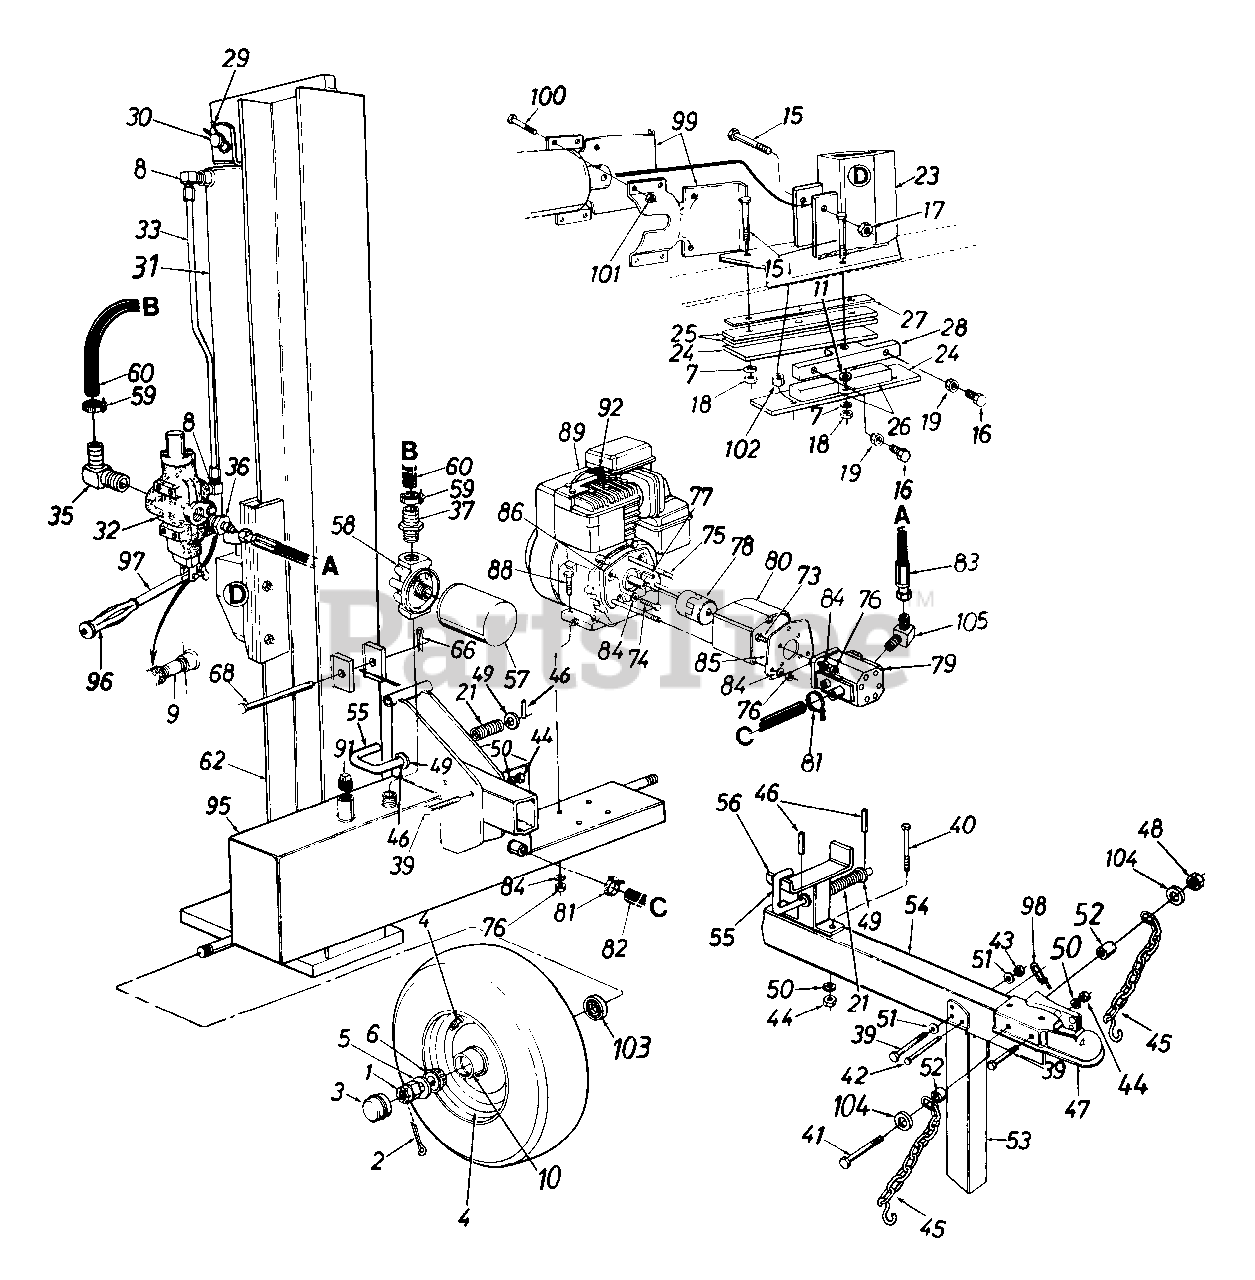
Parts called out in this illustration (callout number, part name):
1	Slotted Nut 3/4-16 Thd.
2	Cotter Pin 5/32" Dia. x 1-1/4" Lg.
5	FI-Wash..76" I.D. x 1.5" O.D.
6	Bearing Cone
7	L-Wash. 1/2" I.D.
8	90 deg. Solid Male Adapter
9	Pipe Nipple 1/2 NPT
10	Bearing Cup
11	FI-Wash..531" I.D. x.94" O.D.
15	Hex Bolt 1/2-20 x 2.75" Lg. (Grade 8)
16	Hex Bolt 3/8-24 x 1.5" Lg.
17	Hex L-Nut 1/2-20 Thd.
18	Hex Nut 1/2-20 Thd.
19	Hex Jam Nut 3/8-24 Thd. (Grade 5)
21	Comp. Spring 4" Lg.
26	Adjustable Gib
29	External Cotter Pin
30	Cylinder Mounting Pin
33	Metal Pressure Tube
35	Return Elbow
37	3/4" Hose Barb.
39	Hex Bolt 3/8-16 x 2.75" Lg. (Grade 8)
40	Hex Bolt 3/8-16 x 4" Lg.
41	Hex Bolt 3/8-16 x 4" Lg. (Grade 5)
42	Clevis Pin 5/16 x 2.5" Lg.
43	Hex L-Nut 3/8-16 Thd.
44	Hex Nut 3/8-16 Thd.
45	Chain -- Tow Hitch
47	Hitch Coupler
48	Hex Ctr. L-Nut 3/8-16 Thd.
49	FI-Wash..635" I.D. x .93" O.D.
50	L-Wash. 3/8" I.D.
51	Fl-Wash..406" I.D. x .75" O.D.
52	Spacer 3/8" I.D. x .625" O.D.
55	Locking Rod
57	Filter Element
58	Filter Head
59	Hose Clamp 5/8"
60	Return Hose 3/4" I.D. x 44" Lg.
68	Hinge Pin 1/2 x 4.8" Lg.
73	Hex Bolt 5/16-24 x 1" Lg.
74	Hex Bolt 5/16-24 x .62" Lg.
75	Hex Bolt 5/16-24 x 4" Lg.
76	Hex Nut 5/16-24 Thd.
77	Sq.-Key 3/16" x .75"
78	Flexible Coupling
79	Gear Pump
80	Coupling Shield
81	Hose Clamp
82	Suction Hose
83	High Pressure Hydraulic Hose
84	L-Wash. 5/16" I.D.
88	Hex Bolt 5/16-24 x 1.75" Lg.
89	Engine
91	L-Vent Pipe Plug
92	Spark Plug Boot
97	Control Handle
98	Spring Pin
101	Hex L-Nut 3/8-16 Thd.
102	Spacer 1/2" I.D. x .68" Lg.
103	Bearing Seal Only
104	Fl-Wash. 3/8" I.D. x .87" O.D.
105	90 deg. Male Adapter
